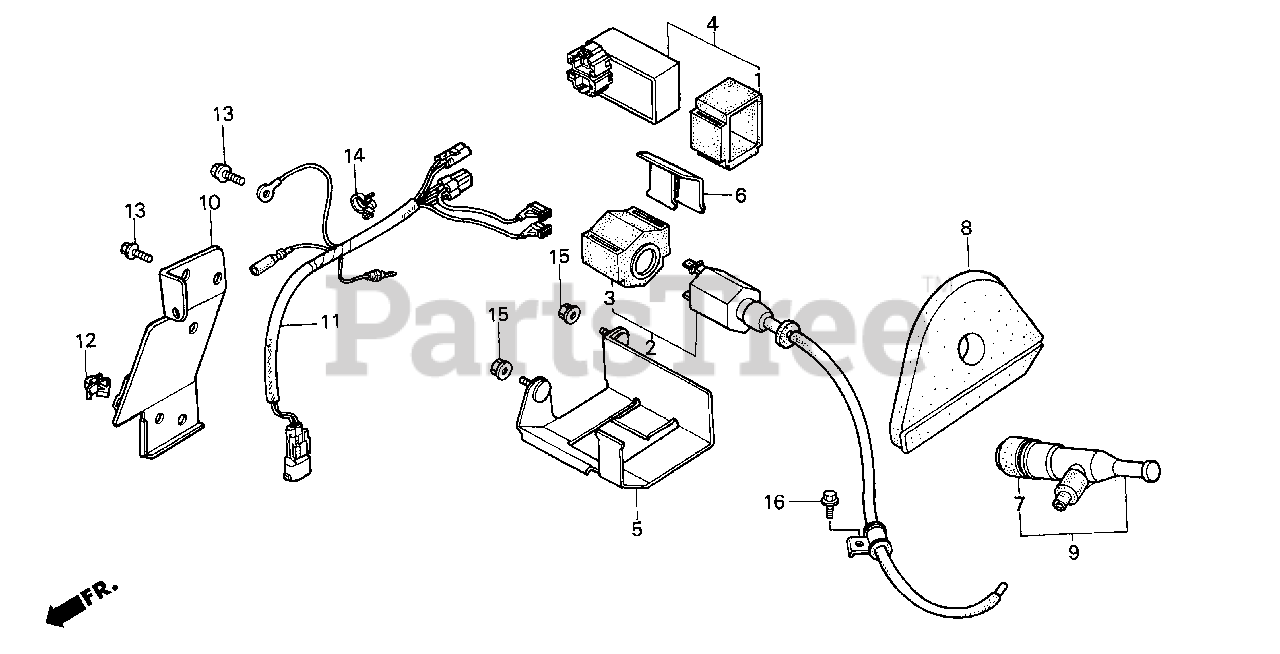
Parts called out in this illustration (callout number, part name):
1	CUSHION, IGNITION CONTROL MODULE (CDI)
2	COIL ASSY., IGNITION
3	SUSPENSION, IGNITION COIL
4	MODULE ASSY., IGNITION CONTROL (CDI)
5	HOLDER, IGNITION COIL
6	PLATE, IGNITION
7	SEAL, IGNITION TERMINAL
8	SEAL, IGNITION
9	CAP ASSY., NOISE SUPPRESSOR (NICHIWA Y-EZA)
10	BASE, HARNESS CLIP
11	HARNESS ASSY., ENGINE
12	CLIP B, HARNESS
13	BOLT, FLANGE (6X12) (CT200)
14	CLIP B, CABLE (9MM BLACK)
15	NUT, FLANGE (6MM)
16	BOLT, FLANGE (6X8)
